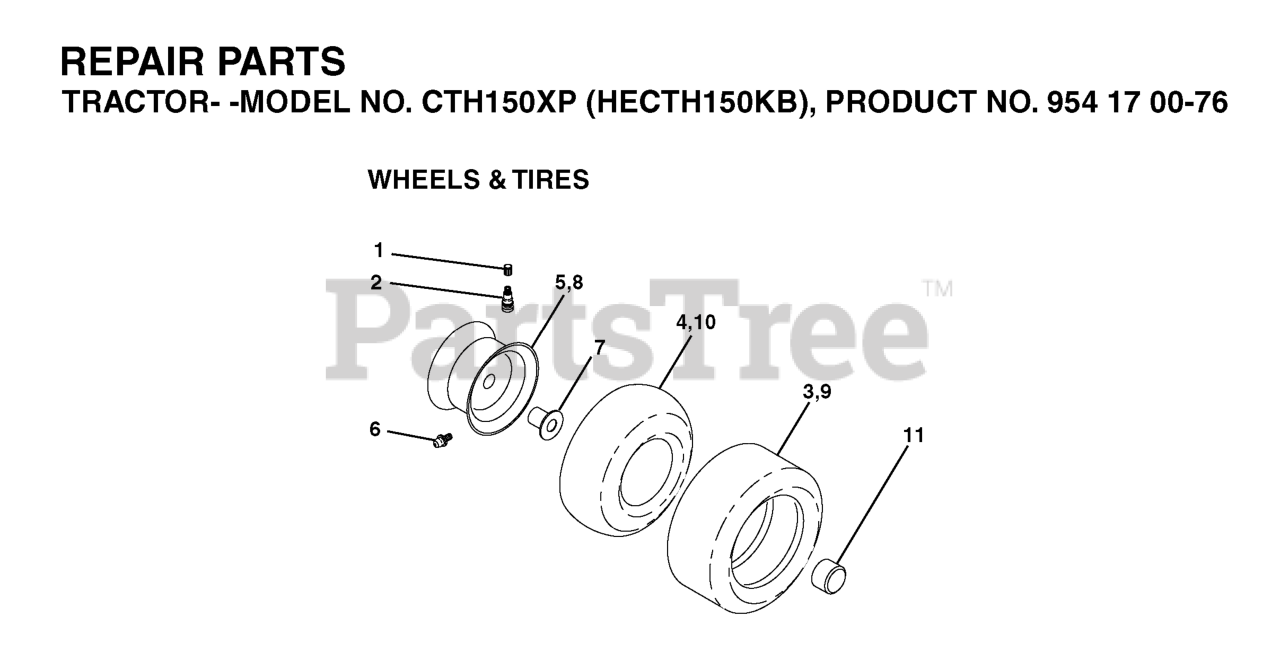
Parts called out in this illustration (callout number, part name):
2	VALVE STEM LT
3	TIRE HEAVY DUTY
4	TUBE.5.3/4.5/6
5	RIM ASM 6" FRONT SILVER
6	FITTING LT
7	BEARING T
8	RIM ASM 8" REAR SILVER
9	TIRE.20X8-8.TURF.SAVER
10	TUBE
11	CAP, AXLE BLK
